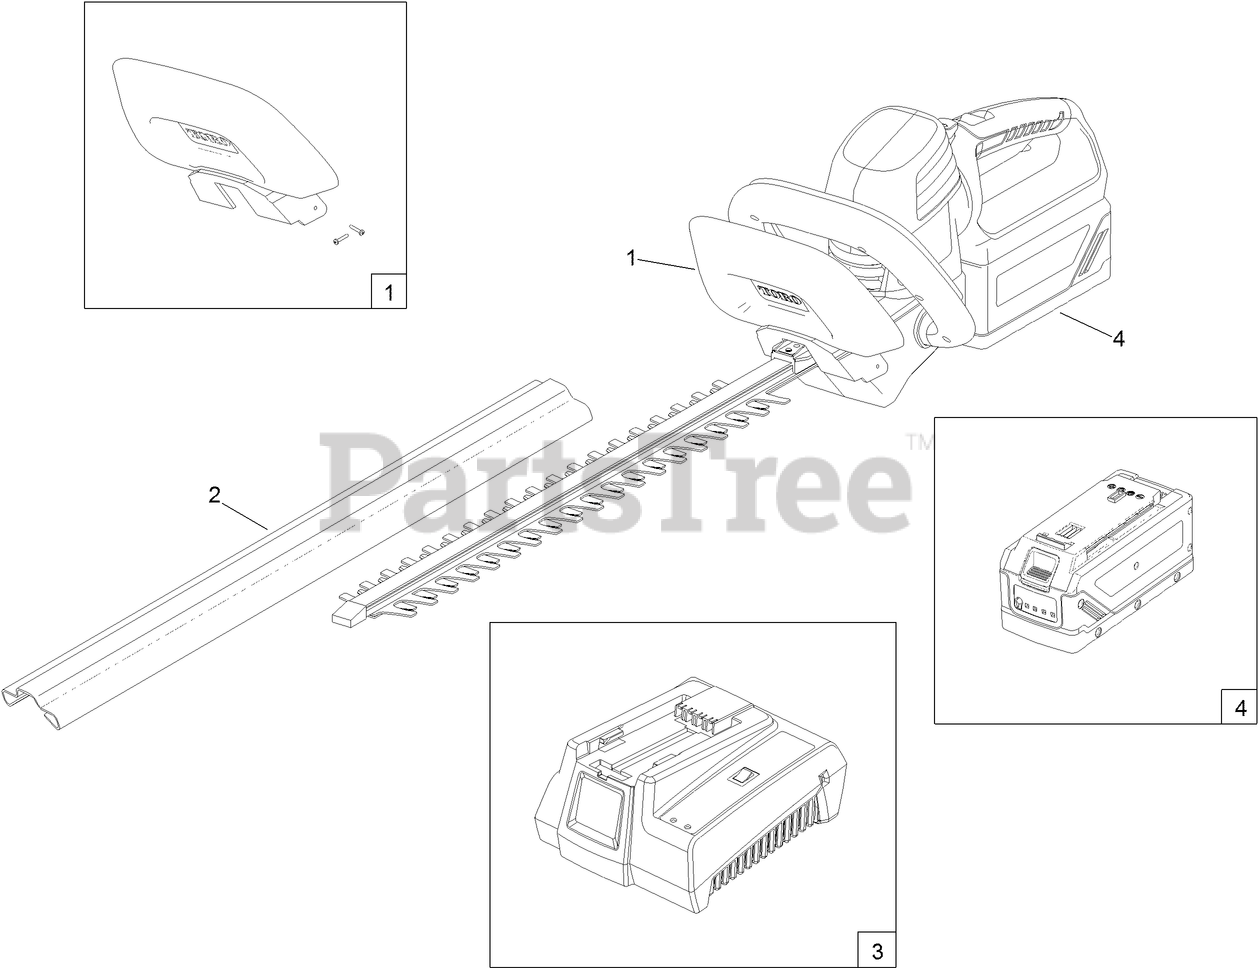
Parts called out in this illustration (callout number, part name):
1	GUARD ASM
2	SHEATH-BLADE
3	CHARGER-REPLACEMENT, 48V
4	BATTERY-REPLACEMENT, 48V
